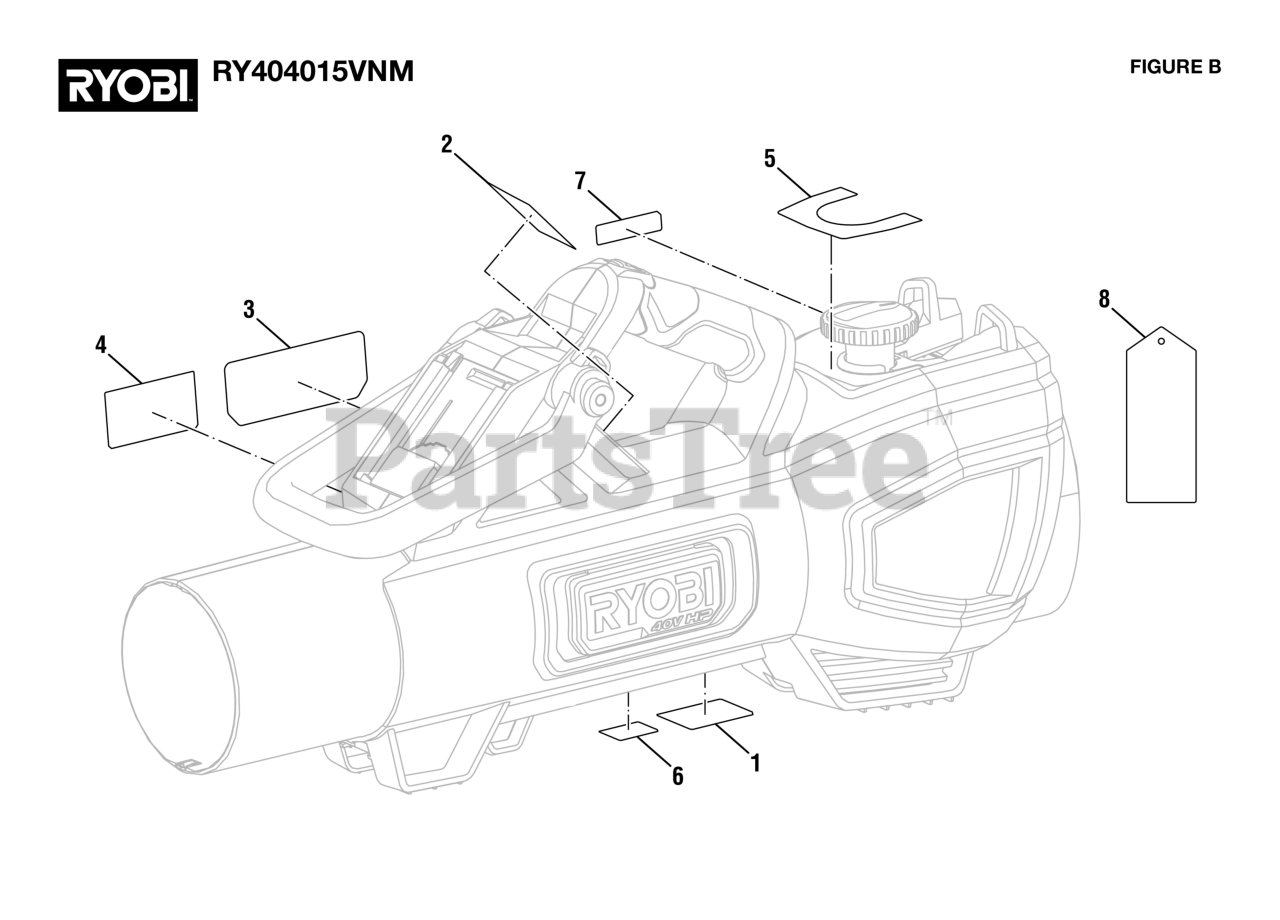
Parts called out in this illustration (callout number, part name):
1	Data Label
2	Icon Label
3	Warning Label
4	Caution Label
5	Dial Label
7	Ingestion Icon Label
8	Installation Hangtag
